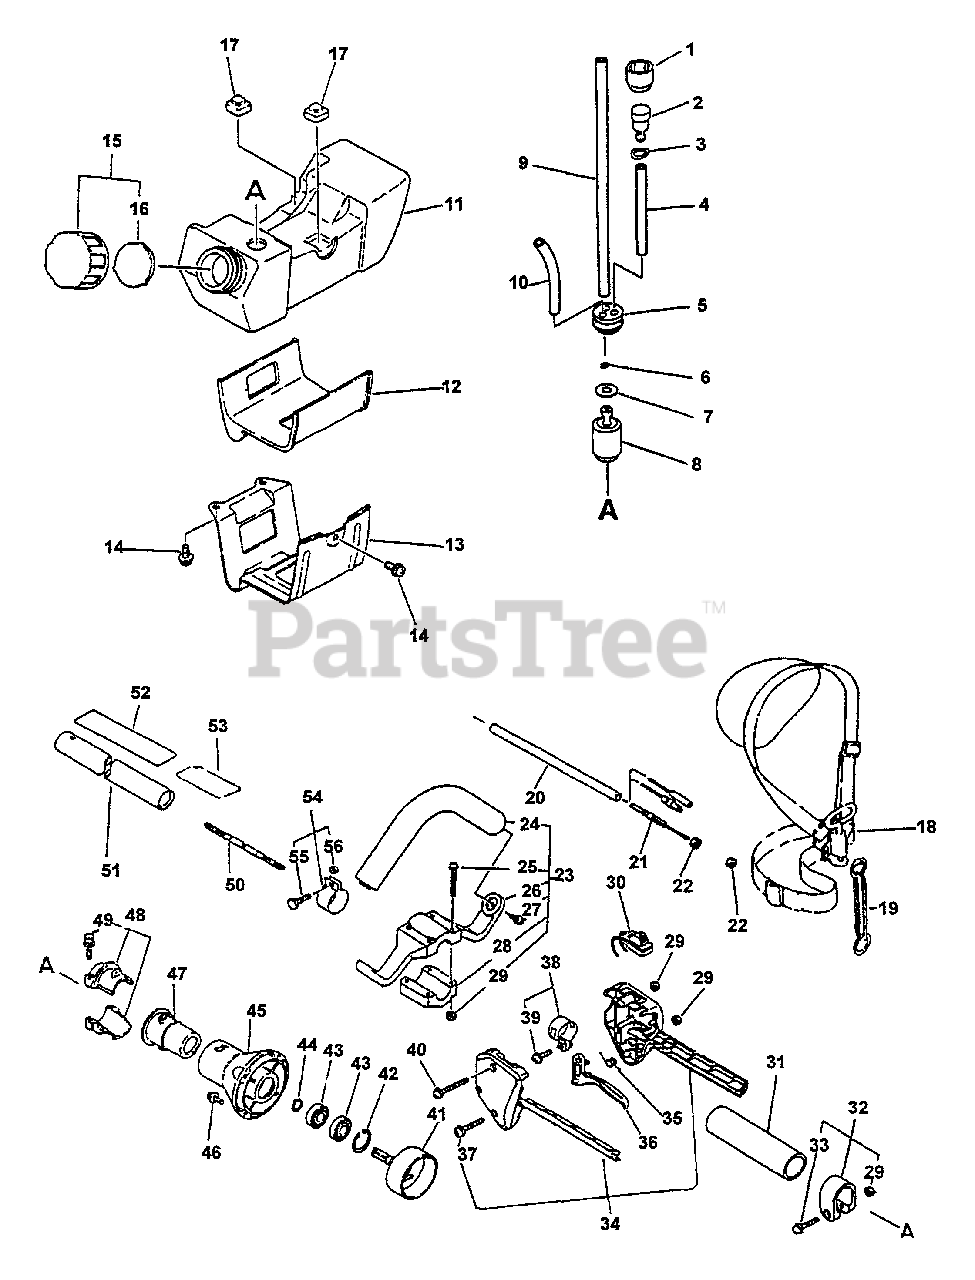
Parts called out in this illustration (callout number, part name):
1	COVER, VENT
2	VENT, FUEL TANK
3	CLIP - 6
4	PIPE - 3X6X70 -- BLACK
5	GROMMET
6	CLIP - 5.5
7	WASHER - 5
8	FILTER, FUEL
9	PIPE - 3X5X180 -- BLACK
10	PIPE - 3X6X90 -- CLEAR
11	TANK, FUEL
12	CUSHION
13	GUARD, FUEL TANK
14	SCREW - 5X10
15	CAP ASSY
16	GASKET, CAP
17	CUSHION
18	SHOULDER STRAP ASSY
20	TUBE - VINYL
21	CABLE, THROTTLE
23	LOOP HANDLE ASSY
24	HANDLE - FRONT
25	SCREW - 5X35
26	BRACKET, HANDLE - UPPER
27	SCREW - 5X14
28	BRACKET, HANDLE - LOWER
30	IGNITION SWITCH ASSY
31	GRIP, HANDLE
32	CLAMP KIT
33	SCREW - 5X28
34	CONTROL HANDLE KIT
35	SPRING, TRIGGER
36	TRIGGER, THROTTLE
37	SCREW - 5X25
38	CLAMP KIT
39	SCREW - 5X14
40	SCREW - 5X35
41	DRUM, CLUTCH
42	RING, RETAINING - 28
43	BEARING, BALL - 6001
44	RING, RETAINING - 12
45	CASE, CLUTCH - GRAY
46	SCREW - 5X16
48	HOLDER KIT
49	BOLT - 5X25
50	DRIVESHAFT
51	PIPE, MAIN
52	LABEL - CAUTION
53	LABEL - CAUTION
55	BOLT - 5X18
